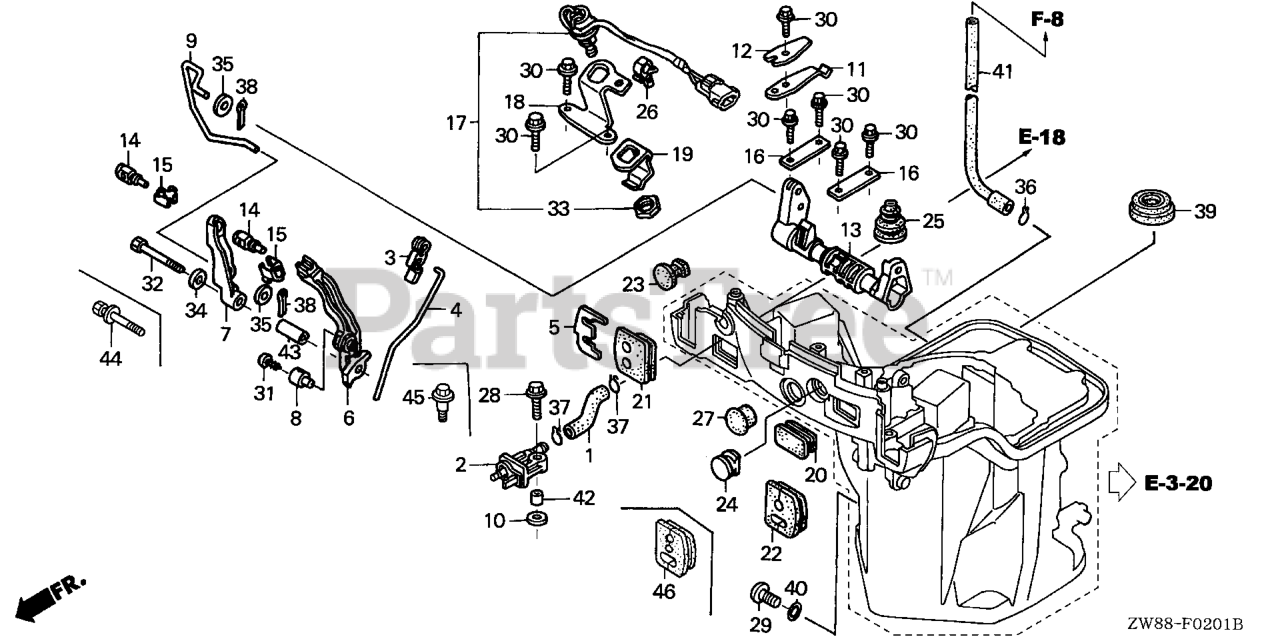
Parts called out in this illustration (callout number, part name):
1	TUBE A, FUEL
2	CONNECTOR ASSY., FUEL (B)
3	LINKAGE, PIVOT
4	ROD, THROTTLE
5	PLATE, REMOTE CONTROL CABLE
6	ARM, THROTTLE REMOTE
7	ARM, SHIFT LINK
8	HOLDER, THROTTLE ROD
9	ROD, SHIFT LINK
10	WASHER, PIVOT
11	SPRING, CLICK
12	SPRING, CLICK ASSIST
13	SHAFT, SHIFT
14	PIVOT, SHIFT
15	PLATE, LOCK
16	PLATE, SHIFT SHAFT
17	SWITCH ASSY., NEUTRAL
17	SWITCH SET, NEUTRAL
18	BRACKET, NEUTRAL SWITCH
19	PLATE, NEUTRAL SWITCH (NOT AVAILABLE)
20	GROMMET G, OIL CASE
21	GROMMET A, OIL CASE
23	GROMMET F, OIL CASE
24	GROMMET D, OIL CASE
25	GROMMET E, OIL CASE
26	CLIP, BRAKE PIPE (A) (FOR NEUTRAL SWITCH)
27	CAP, HANDLE (LOWER)
29	BOLT, OIL CHECK
30	BOLT, FLANGE (5X12) (CT200)
31	BOLT, RECESSED (5X8)
33	NUT, HEX. (20MM) Use up to Frame SN 1300359.
35	WASHER, PLAIN (7MM)
36	CLIP, TUBE (B10)
37	CLIP, TUBE (B12)
38	PIN, SPLIT (2.0)
39	SEAL, WATER (13X28X7) (ENGINE NO.)
40	O-RING (5.5X1.5)
41	TUBE, WATER CHECK
43	COLLAR, DISTANCE (6X11X27)
44	BOLT-WASHER (6X40)
45	BOLT, SPECIAL (6X22) (CT200)
46	GROMMET B, OIL CASE (PT)
